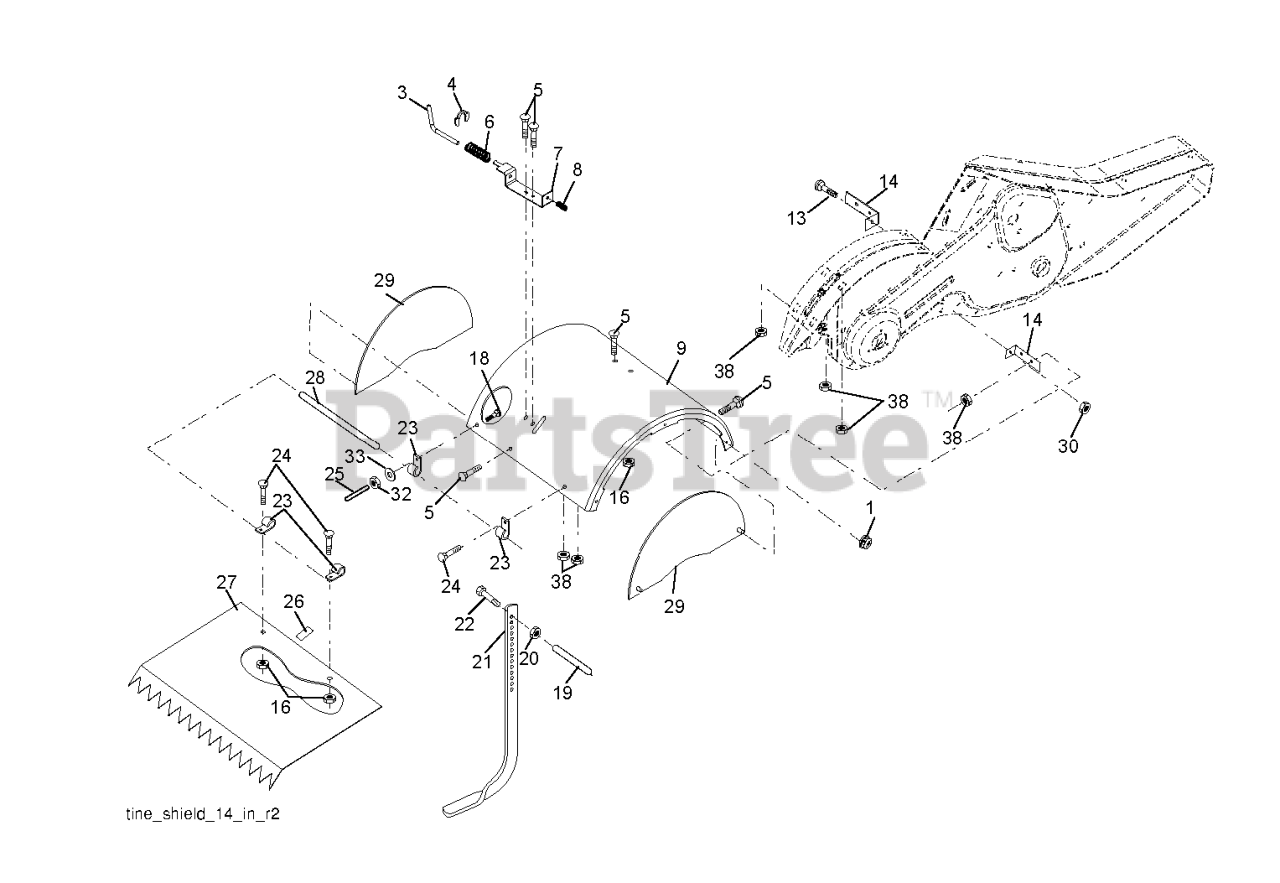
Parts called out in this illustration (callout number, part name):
1	NUT LOCK HEX FLANGE 5/16-18
3	STAKE PIN TI
4	RING, KLIP
5	BOLT, RDHD SQNK 5/16-18 X 3/4
7	BRACKET.LATCH.STAKE.3.20.BLACK
8	SPRING CRT
9	SHIELD.TILLER.TINE.CRT14.ORNG
13	BOLT.CARRIAGE.5/16-18
14	BRACKET.TINE.SHIELD.TILLER
16	NUT T
20	NUT.HEX.3/8-16UNC
21	STAKE.DEPTH.16.CRT.BLACK
22	BOLT.375-16
24	BOLT
25	VINYL CAP TI
26	PAD IDLER TI
27	SHIELD.PNT.LEVEL.CRT.14.ORANGE
28	PIN.HINGE.TILLER
29	SHIELD.TINE.SIDE.ORANGE.TILLER
30	LOCKNUT-FLANGE 5/16-18
32	NUT
33	LOCKWASHER
38	NUT
